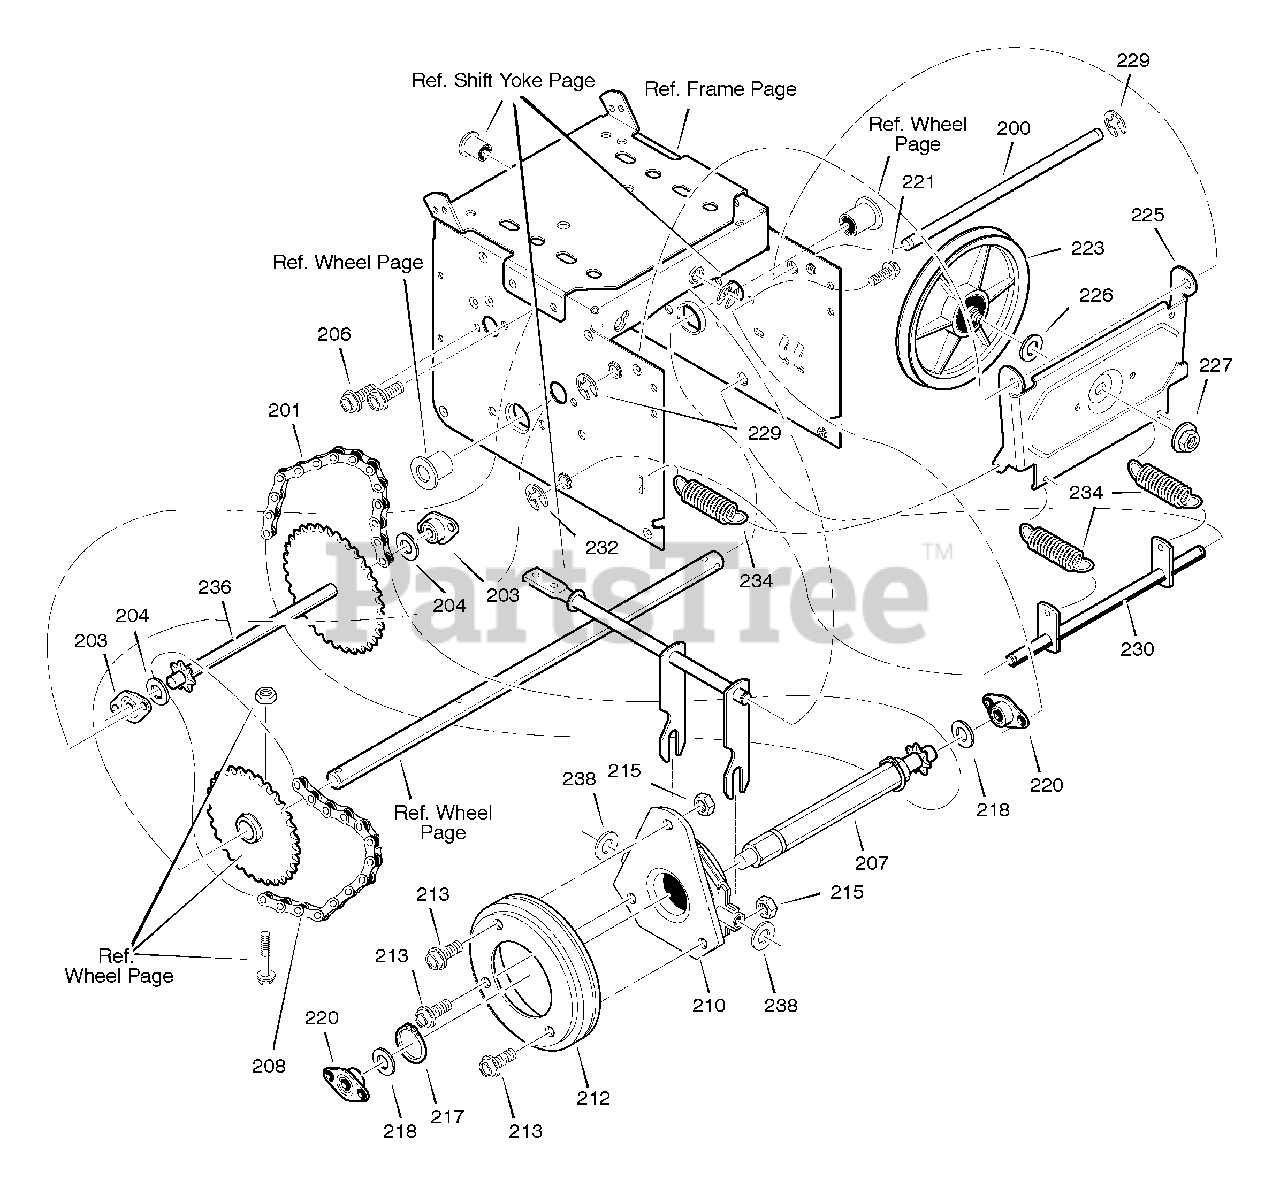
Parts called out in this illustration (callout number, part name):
200	LF AXLE, SWING PLATE YZ
201	CHAIN, ROLLER #420x19.00
203	BEARING AND RETAINER, ASSY
204	WASHER
206	SCREW, TAP 5/16-18 x 0.5
207	ASSY, HEX SHAFT
208	CHAIN, ROLLER #420x18.00 LG
210	BEARING, TRUNION CLUTCH R
212	WHEEL, FRICTION DISC
213	BOLT
215	NUT, KEPS HEX 1/4-20
217	RING, RETEXT
218	WASHER
220	BEARING AND RETAINER, ASSY
221	SCREW, TAP 5/16-18 x 0.5
223	FRICTION PULLY
225	LF PLATE, SWINGING YZ
226	SPACER, FRICTION PULLEY
227	NUT, FLANGE LOCK 3/8-24
229	RETAINER, RING
230	LF ASSY, SPRING LINK YZ
232	RETAINER, RING
234	SPRING, EXTENSION
236	SPROCKET 33/7
238	WASHER, FLAT
